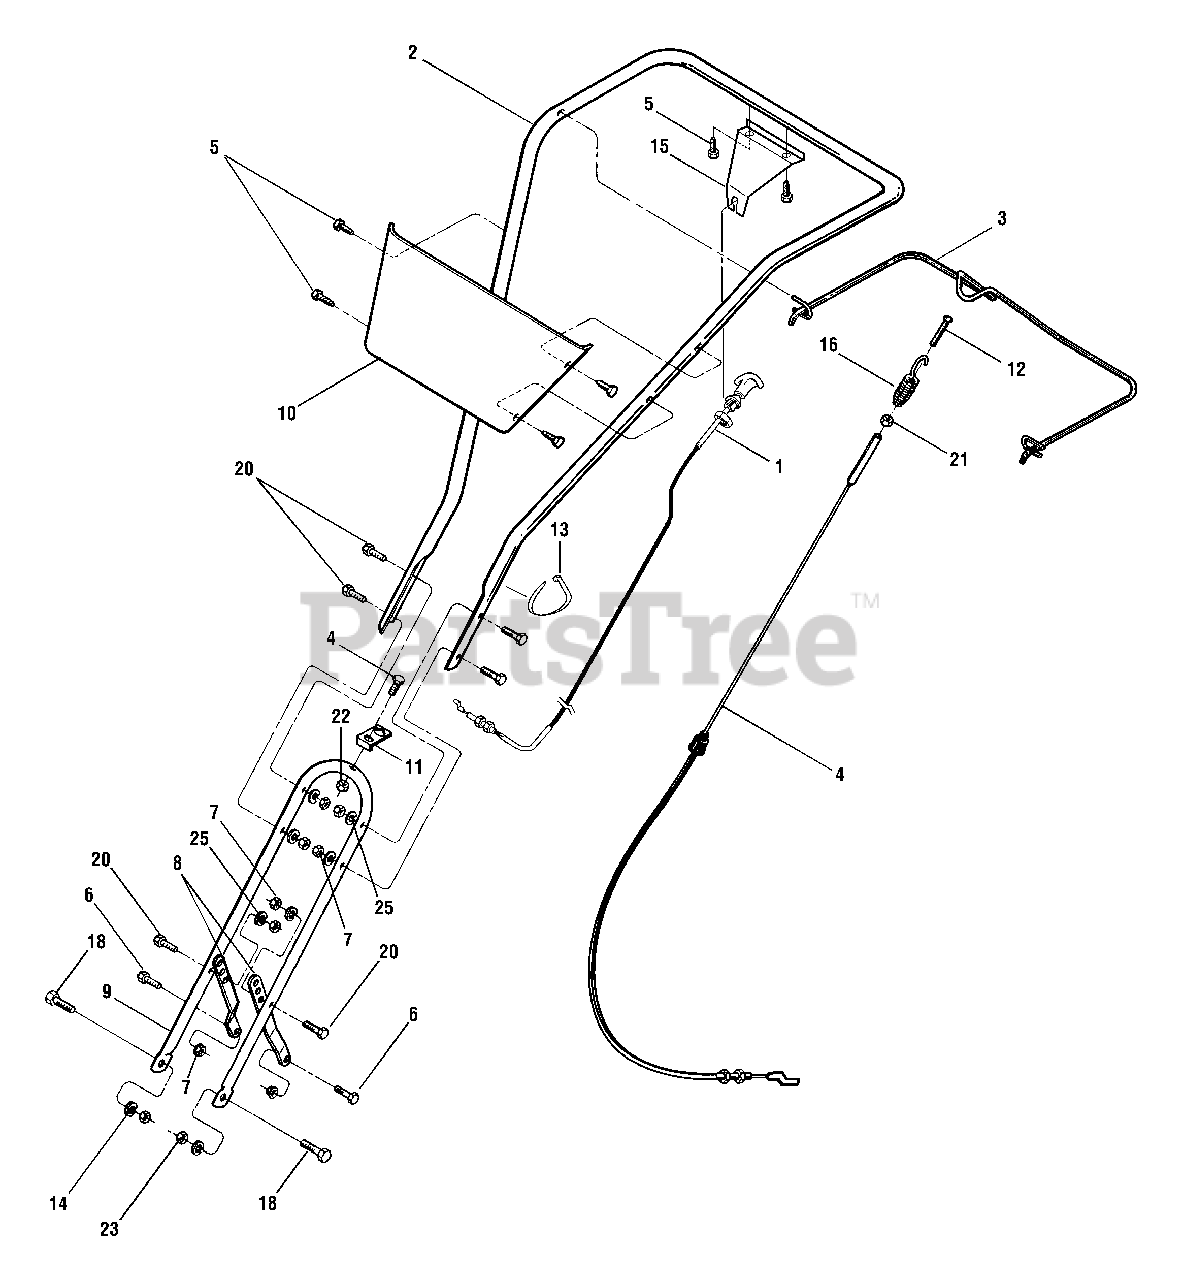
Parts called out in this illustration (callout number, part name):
1	Cable Assembly, Reverse Clutch
2	Upper Handlebar (634)
3	Bail, Forward Clutch
4	Cable Assembly, Forward Clutch
5	Screw, Self-Tapping,1/4-20 x 1/2
6	Screw, Hex, 5/16-18 x 3/4
7	Hex Lock Nut, 5/16-18
8	Handlebar Support
9	Lower Handlebar
10	Panel
11	Tab, Conduit Mount
12	Screw, #10-24 x 2
13	Cable Tie
14	Flat Washer, 3/8
15	Bracket, Reverse Clutch Cable
16	Spring, Forward Clutch
18	Screw, Hex, 3/8-16 x 3/4
20	Screw, Hex, 5/16-18 x 1-1/2
21	Hex Nut, #10-24
22	Hex Lock Nut, 1/4-20
23	Hex Nut, 3/8-16
25	Lock Washer, 5/16
